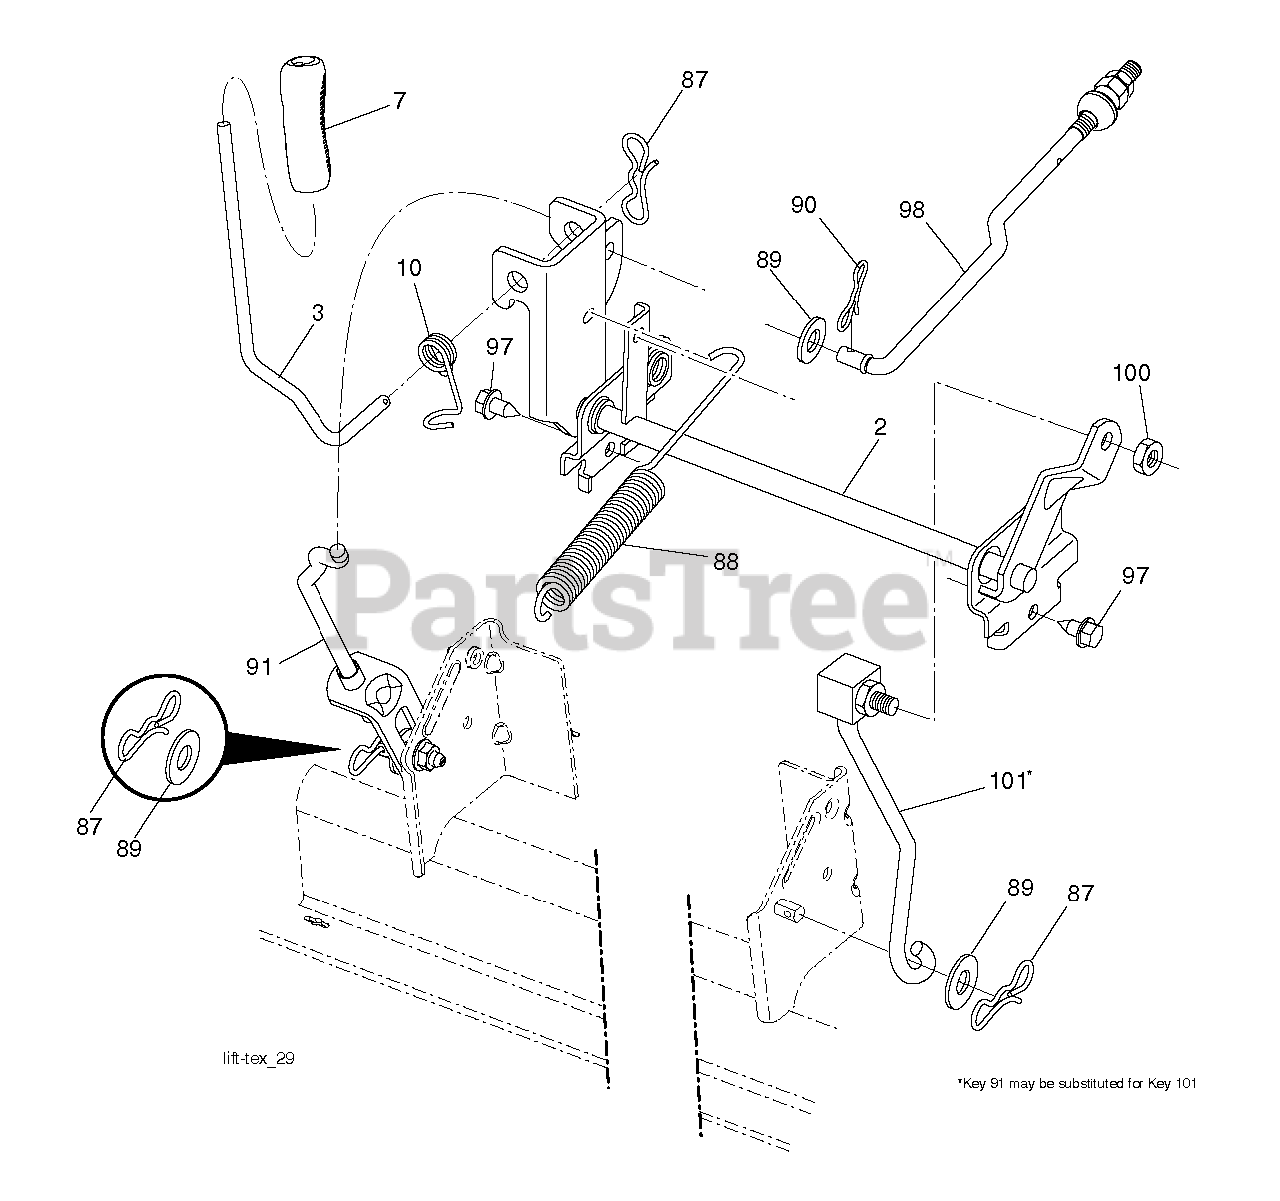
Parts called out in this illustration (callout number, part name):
2	SHAFT.ASM.CROSS.LIFT
3	LEVER.LIFT.HANDLE.GT
10	SPRING.TORSION.LIFT.HANDLE
87	PIN.COTTER.7/16.BOW TI
88	SPRING.LIFT.ASSIST
89	WASHER.CLEAR.ZINC
90	PIN.COTTER.5/16.BOW TI
91	LINK.ASM.LIFT.REAR
97	SCREW, 3/8-16X3/4
98	LINK.ASM.SUSP.FRONT.MWR.10.5
100	LOCKNUT
101	LINK.ASM.LIFT.FIXE.38/42/46"
